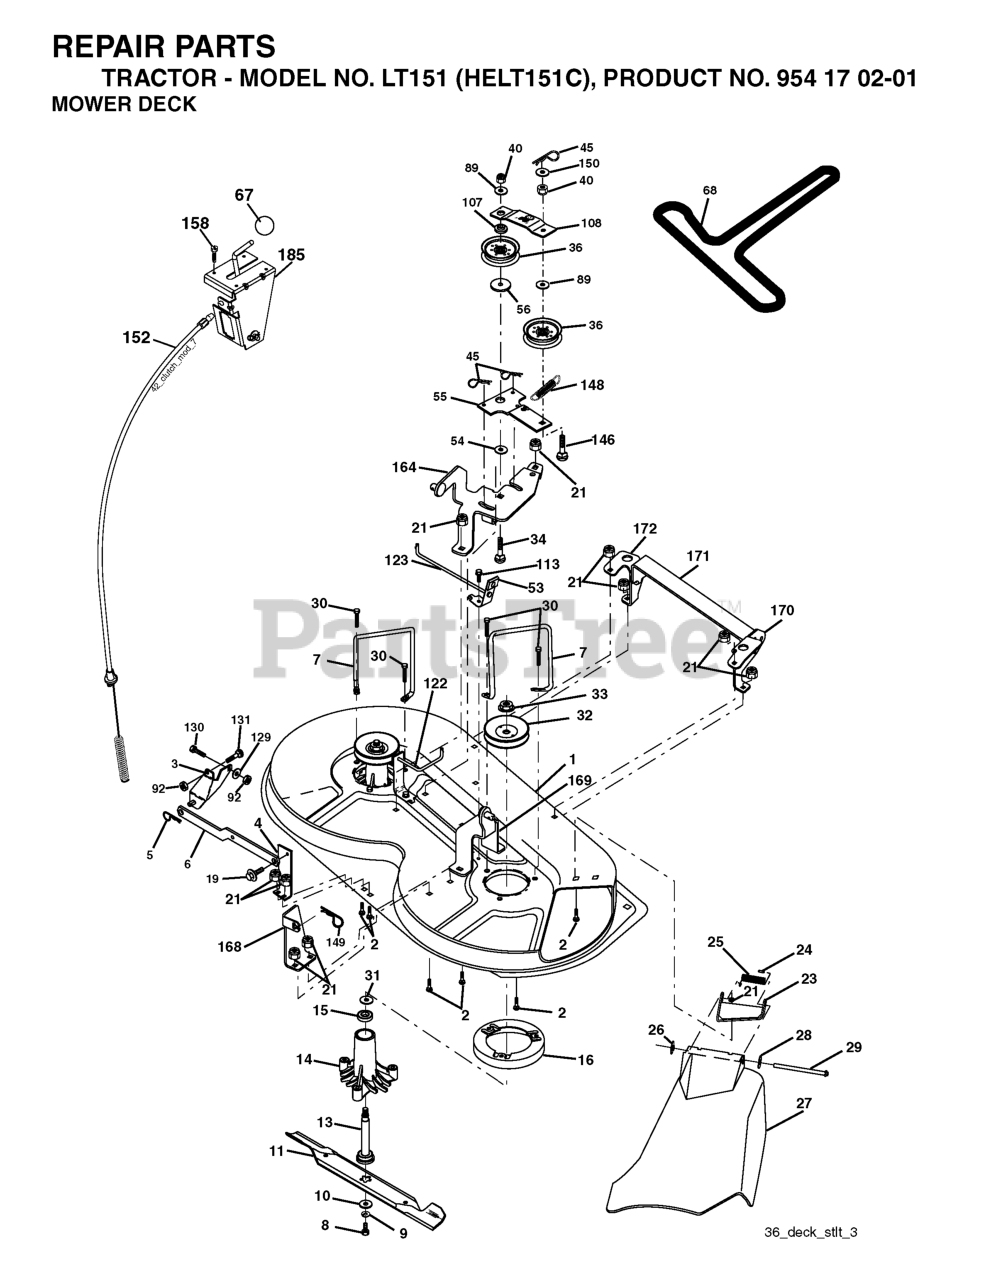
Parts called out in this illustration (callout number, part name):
2	RP BOLT 5/16-18 X3/4 ZN/YEL GR
3	BRKT ASM SWAY BAR
5	RETAINER-SPRNG RB
6	BAR SWAY DECK
8	BLADE BOLT
9	LOCKWASHER
10	WASHER.BLADE
11	BLADE, HI-LIFT 36" PREMIUM
13	SHAFT ASM VENT
14	HOUSING.MANDREL.VENTED (MACHD)
16	STRIPPER.MANDREL.ROUND.BLACK
19	BOLT SHD 5/16-18
21	LOCKNUT
23	BRACKET ASM DEFLECTOR
24	CAP-SLEEVE LT
25	SPRING TORSION
26	NUT PUSH M
27	CONSOLE.STLT.5SP.BLK
28	Washer 11/32 x 5/8 x 16 Ga SD
29	HINGE ROD
30	SCREW, WASHER HEAD
31	WASHER.SPACER.MANDREL
32	PULLEY, MANDREL
33	NUT, FLG TOPLOCK 9/16"
36	FLAT IDLER PULLEY
45	RETAINER M
53	BRAKE ASSEMBLY
56	SPACER.RETAINER.MOWER
67	KNOB T (3/8 HOLE)
68	V-BELT.MOWER.
89	WASHER
92	NUT
107	SPACER.IDLER.ARM
108	STIFFENER.IDLER.ARM
113	Screw 5/16-18 x 1/2 Hex, Self Tapping 5/16-18 x 1/2
129	WASHER
131	BOLT D
146	BOLT, CARRIAGE IDLER
148	IDLER RETURN SPRING
149	SPRING.RETAINER.YELLOW.ZINC
158	SCREW
171	BRACE.SUPT.SUSP.FRT.CRD
185	HEAD ASM. CABLE CLUTCH
